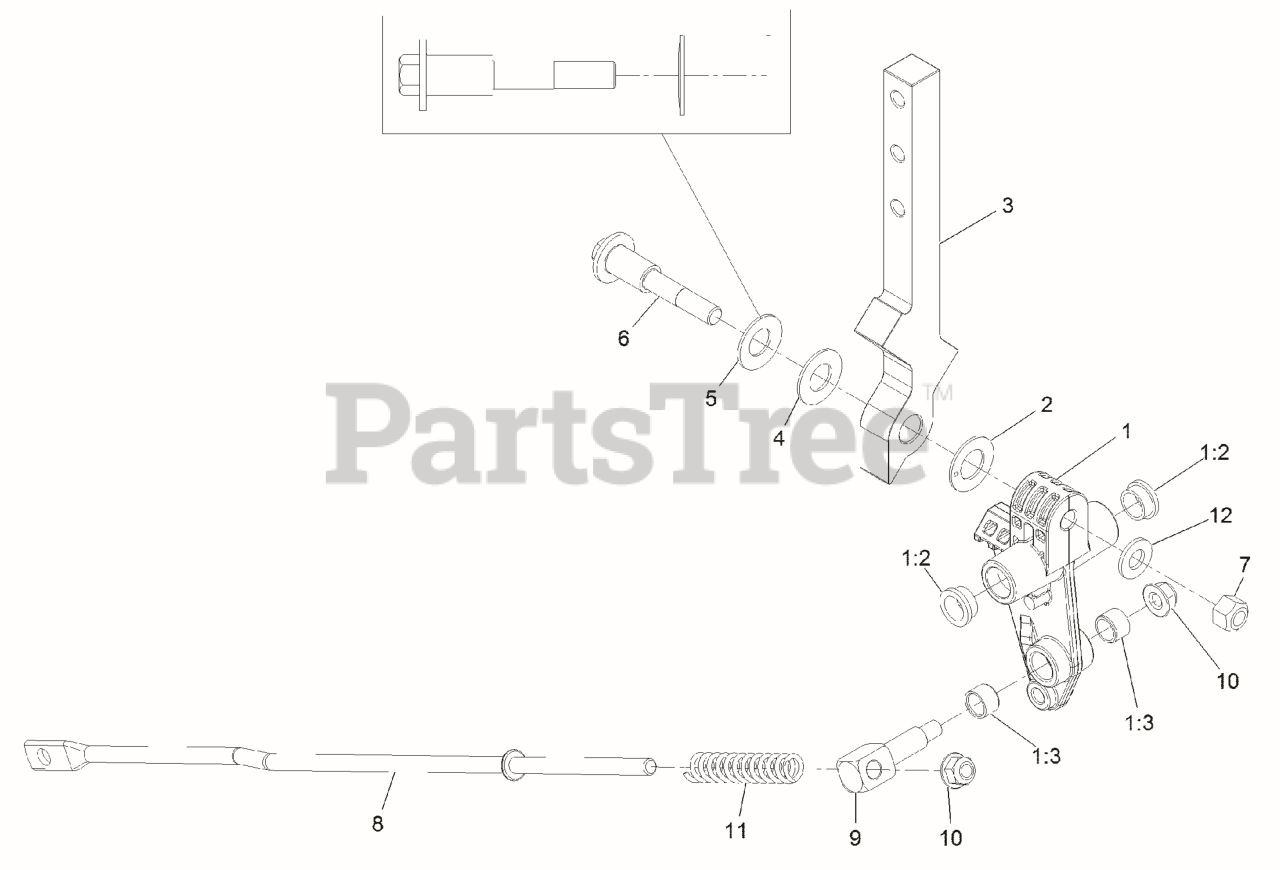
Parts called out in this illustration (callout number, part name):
1	CONTROL ARM ASM
1:2	BUSHING
1:3	BUSHING-SLEEVE
2	WASHER-FRICTION
3	ARM-CONTROL
5	WASHER-BELLEVILLE
6	BOLT-PIVOT
7	NUT-HF, NI
8	LINK-CONTROL
10	NUT-HF, NI
11	SPRING-RETURN, NEUTRAL
